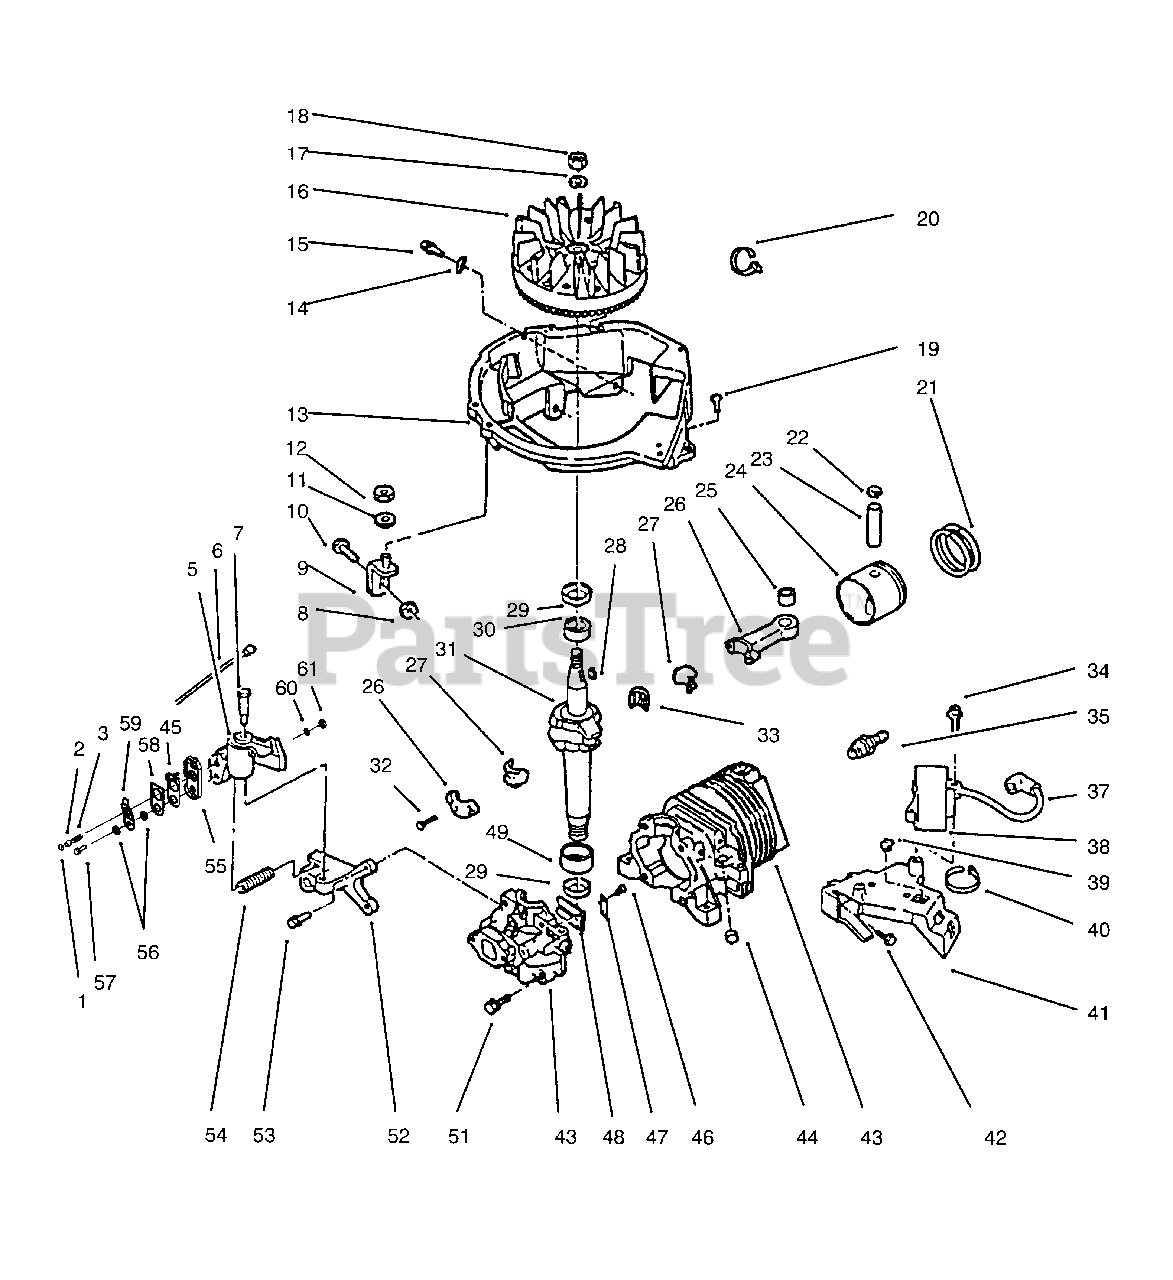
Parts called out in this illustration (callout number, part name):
1	Retainer
2	Actuator-Brake Lever
3	Spring-Cable, Return
5	Brake Assembly
6	Wire Lead
7	Bolt-Shoulder
9	Brace Assembly
13	Shroud-Base
14	"J" Clip
16	Flywheel Assembly
17	Washer-Lock
18	Nut-Flywheel
20	Tie Strap
21	Set-Ring
22	Ring-Retaining
23	Pin-Wrist
24	Set-Piston & Ring (Incl. Ref.# 21 -24)
25	Bearing Assembly
26	Connecting Rod Assembly (Incl. Ref. #25, 27, 32 & 33)
27	Liner-Pair
28	Key-Flywheel
29	Seal-Oil
30	Bearing-Main
31	Crankshaft
33	Set-Needle Bearing
34	Screw
35	Spark Plug
37	Wire Lead & Cover Assy
38	C. D. Ignition Module (Incl. Ref. #37)
39	Grommet
40	Tie Strap
41	Bracket-C. D.
43	Cylinder & Crankcase Cover Assembly (Incl. Ref. #46-48, 51 & 53)
45	Plate-Contact
47	Plate-Reed
49	Bearing-Main
52	Bracket-Brake
54	Spring-Brake
55	Case Assembly
56	Washer
59	Spring-Contact
60	Washer-Ext. Tooth Lock
61	Nut
